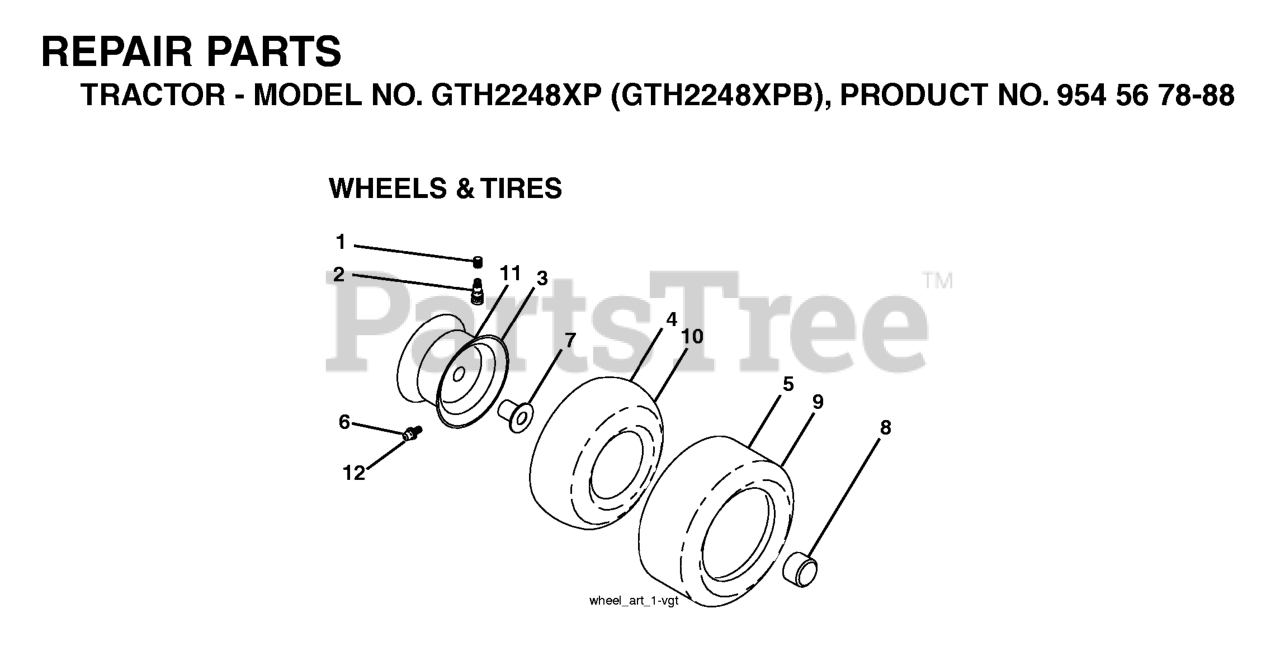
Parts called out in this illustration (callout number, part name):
2	VALVE STEM LT
3	RIM ASSEMBLY, FRONT
4	TUBE.16X6.5/7.5-8
5	TIRE HEAVY DUTY
6	FITTING LT
7	BEARING T
8	CAP, AXLE BLK
9	TIRE HEAVY DUTY
10	TUBE.23X9.5-12
11	RIM.ASM.12X7.REAR.SILVER
12	ZERK FITTING M
